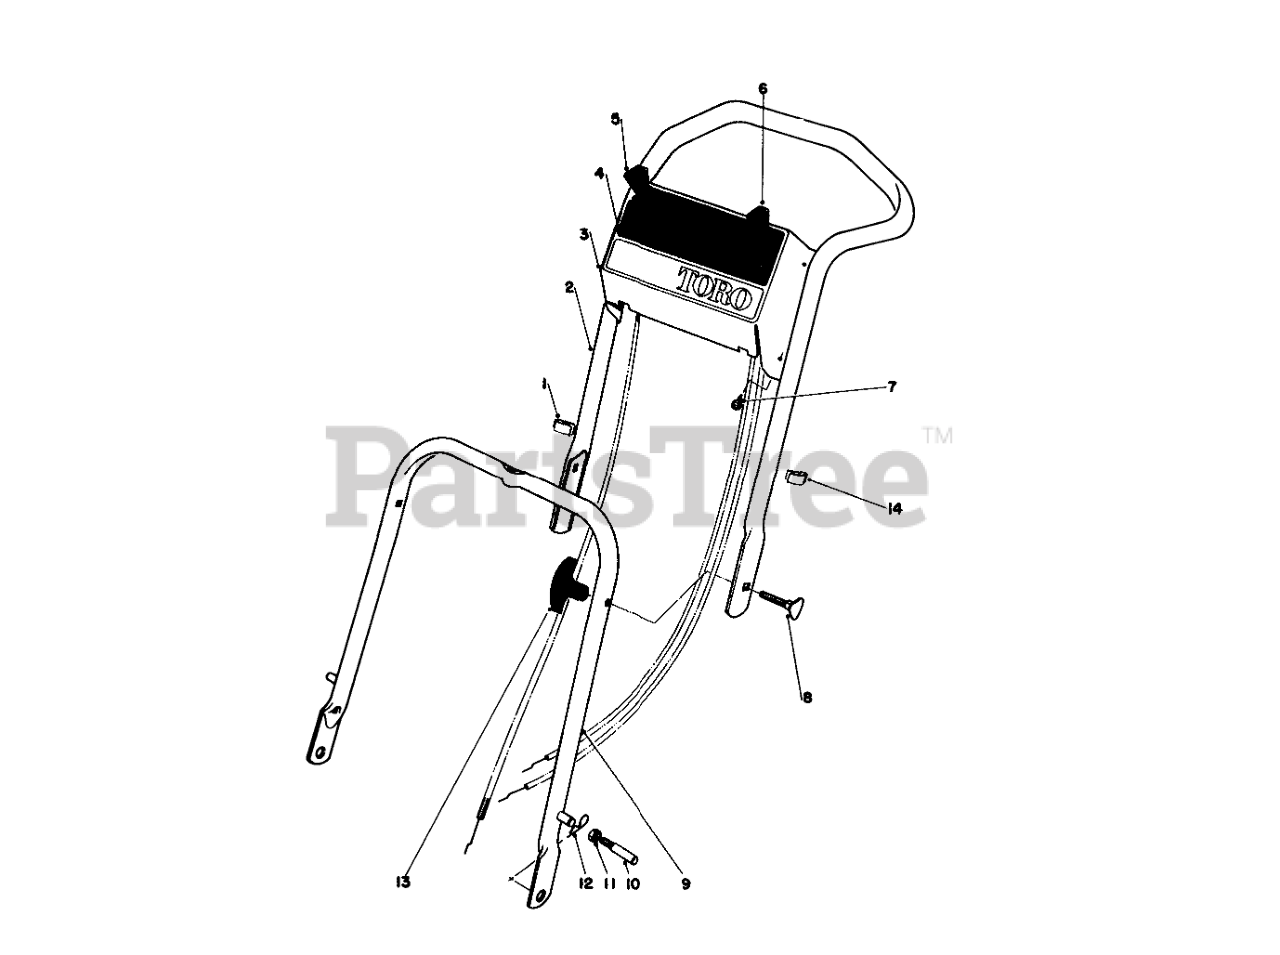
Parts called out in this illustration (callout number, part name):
2	UPPER HANDLE
3	Control Plate
4	Decal-Control Plate (French & Dutch)
5	Throttle Control
6	Traction Control
7	SCREW-HWHTF
8	HANDLE SCREW
9	LOWER HANDLE ASM
10	HANDLE PIN
11	Nut
12	PIN-COTTER, HAIR
14	BOWDEN CLIP
